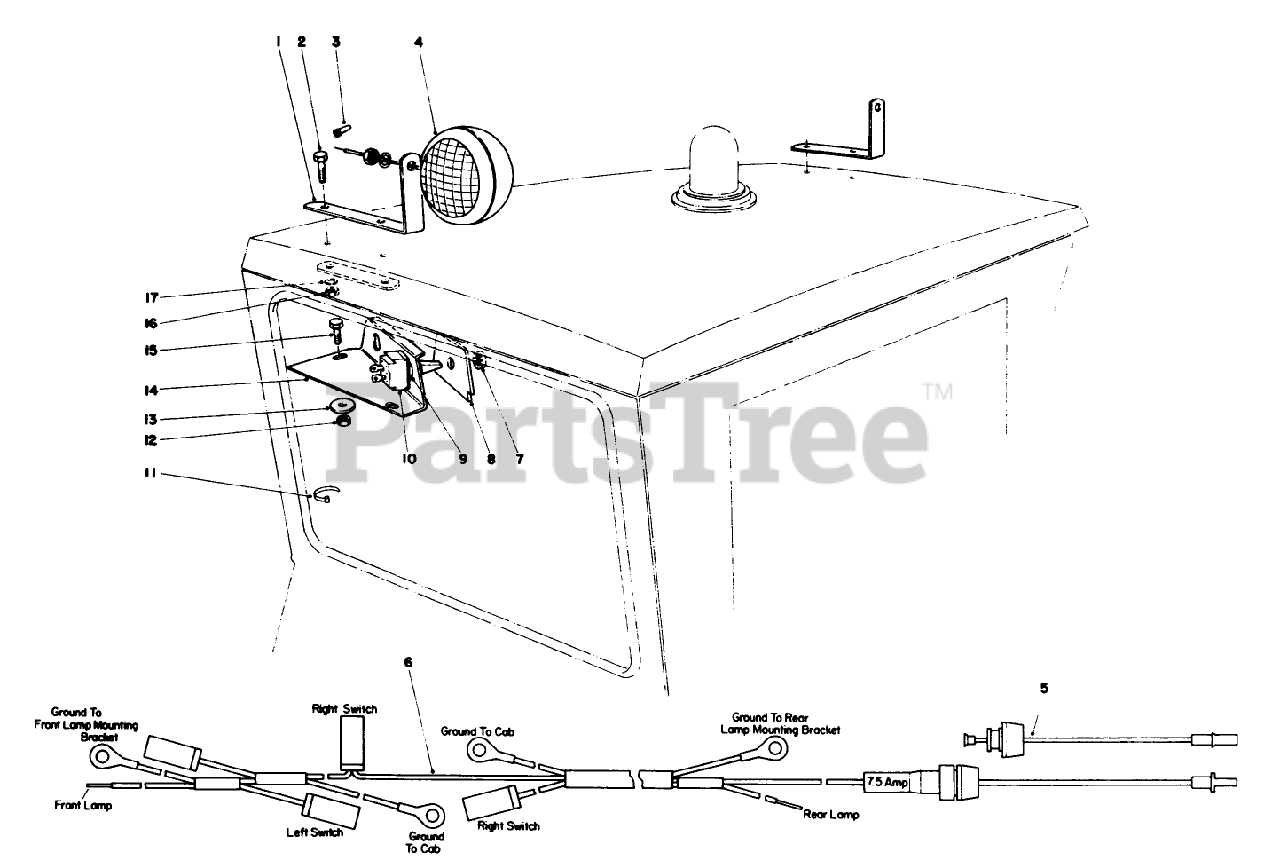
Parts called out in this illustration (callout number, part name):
1	Mounting Bracket Headlamp
2	SCREW-HH
3	Connector
4	Lamp Assy.
6	Wire Harness
7	NUT-BULB
8	DASH PANEL INSERT
9	NUT-LOCK
10	Light Switch
11	TIE-CABLE
12	NUT-HEX, SIDE DEFORM
13	WASHER-FLAT
14	Mounting Plate, Switch
15	SCREW-HH
16	NUT-HEX
17	WASHER-LOCK
